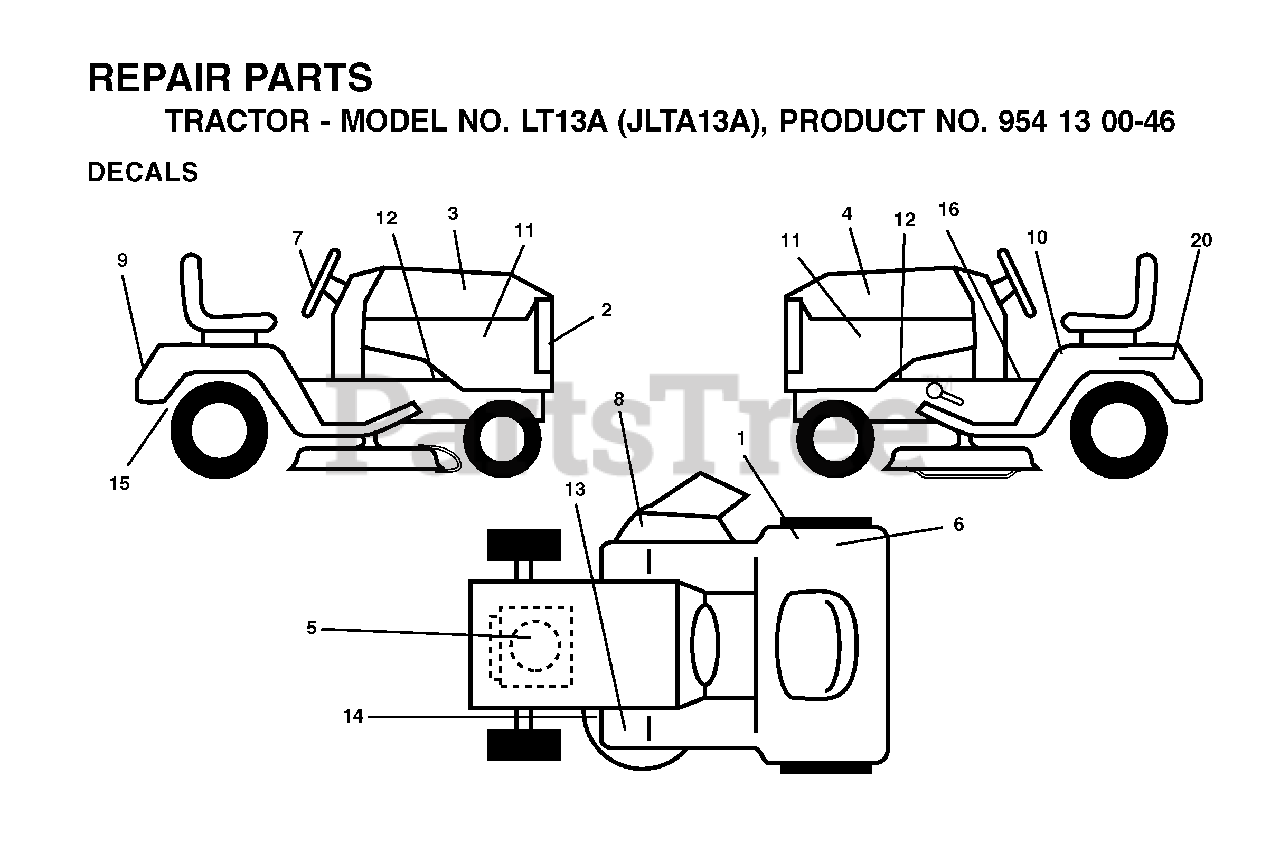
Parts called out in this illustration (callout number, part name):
1	DECAL CERTIFICATION
5	DECAL HP ENGINE
6	DECAL EUROPE STANDARD CE
8	DECAL MOWER CUT/FINGER
10	DECAL READ OWNER'S MAN SYMS
14	DECAL V-BELT SCHEMATIC
16	DECAL PARK BRAKE
20	DECAL BTRY SYMBOLS
